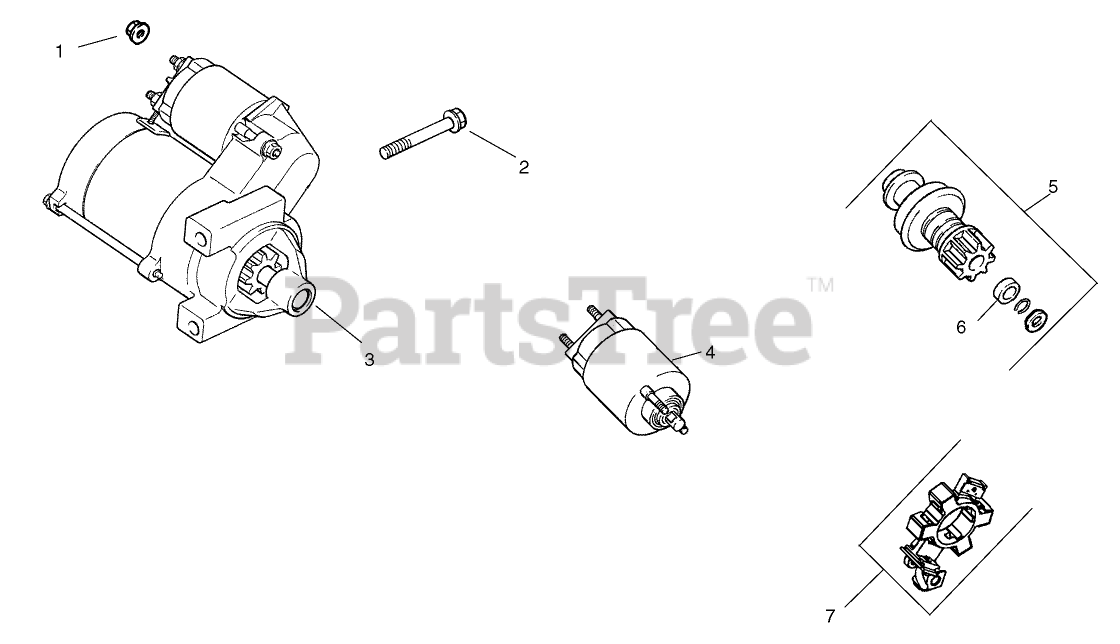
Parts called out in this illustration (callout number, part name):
1	NUT-FLANGE (M8X1.25)
2	SCREW-FLG (M8X1.25X80)
3	STARTER ASM (SOLENOID SHIFT)
4	Solenoid Kit
5	Kit-Drive, Pinion (Includes Ref # 6)
6	RING-RETAINING
7	BRUSH HOLDER KIT
